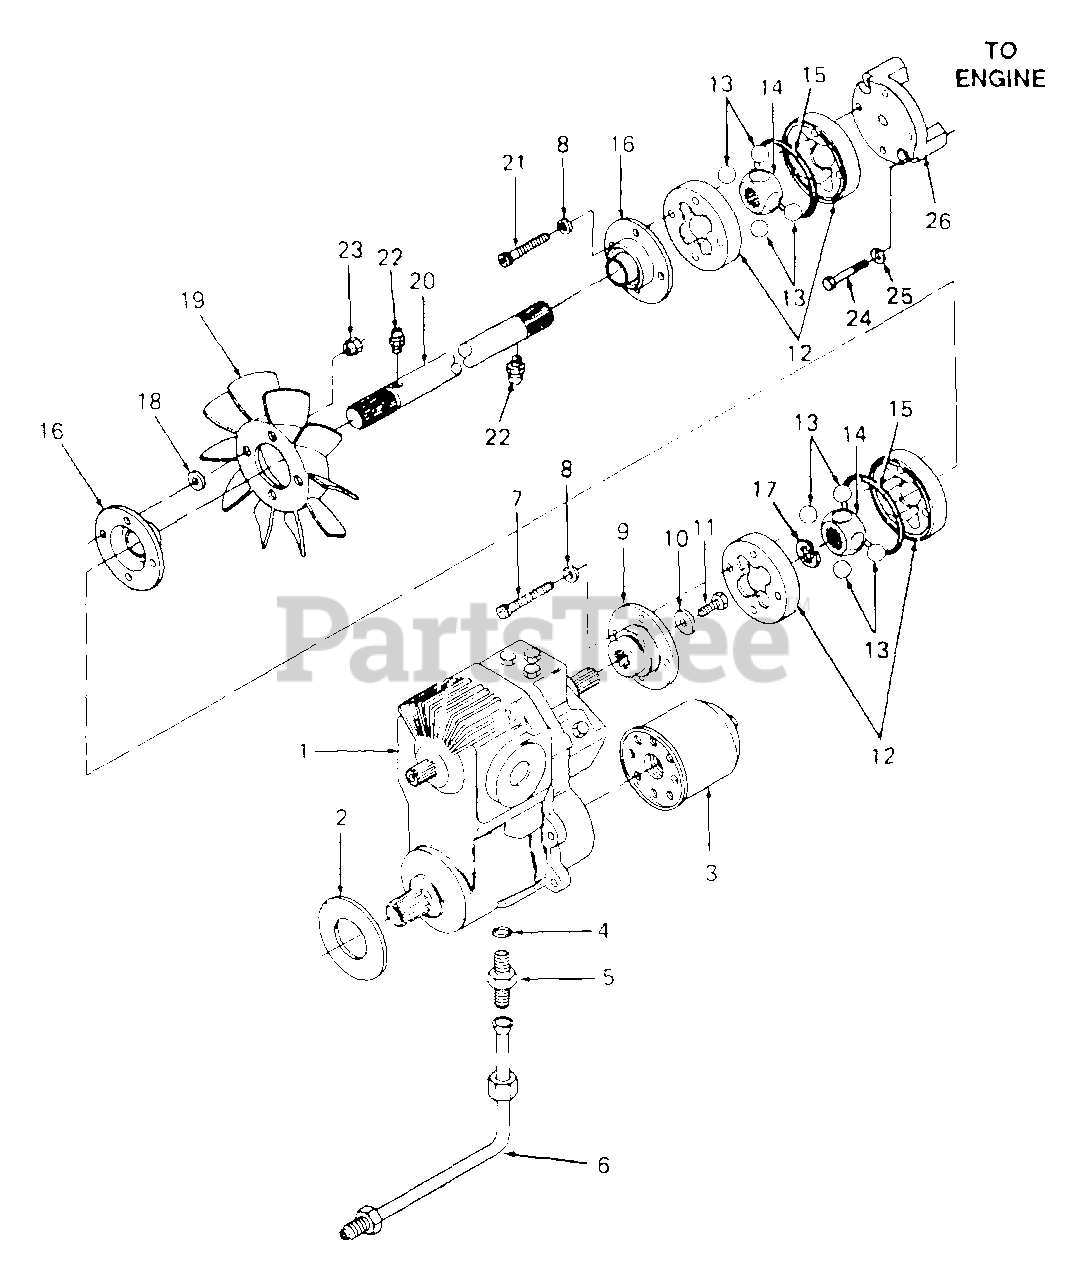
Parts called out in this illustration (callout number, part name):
1	Pump, Hydrostatic
2	Gasket, Front
3	Filter, Oil
4	O-Ring, 5/8 OD Tube
5	Connector, 37 Degree
6	Tube Assy
7	Screw, Socket Hd Cap, 1/4-20 x 2.0 Lg
8	Washer, Lock, 1/4
9	Adapter, Pump
10	Washer, Bell, .265 x .75 x .062 Thk
11	Bolt, Hex Patch, 1/4-20 x 1.0 Lg GR5
12	Coupling, Drive w/O-Ring Groove
13	Ball, Steel, 5/8 Dia Chrome
14	Hub, Drive
15	O-Ring, 2.489 x .070
16	Boot, Coupling
17	Ring, Snap
18	Washer, Flat, .25 x .62 x .052 Thk
19	Fan, 10 Blade Hydro
20	Shaft, Drive, 26.15 Lg
21	Screw, Socket Hd Cap, 1/4-20 x 1.75 Lg
22	Fitting, Grease
23	Nut, Fan 1/4-20
24	Bolt, Hex Patch, M8-1.25 x 50 MM
25	Washer, Flat, .312 x .750 x .119 Thk
26	Adapter, Drive Shaft
